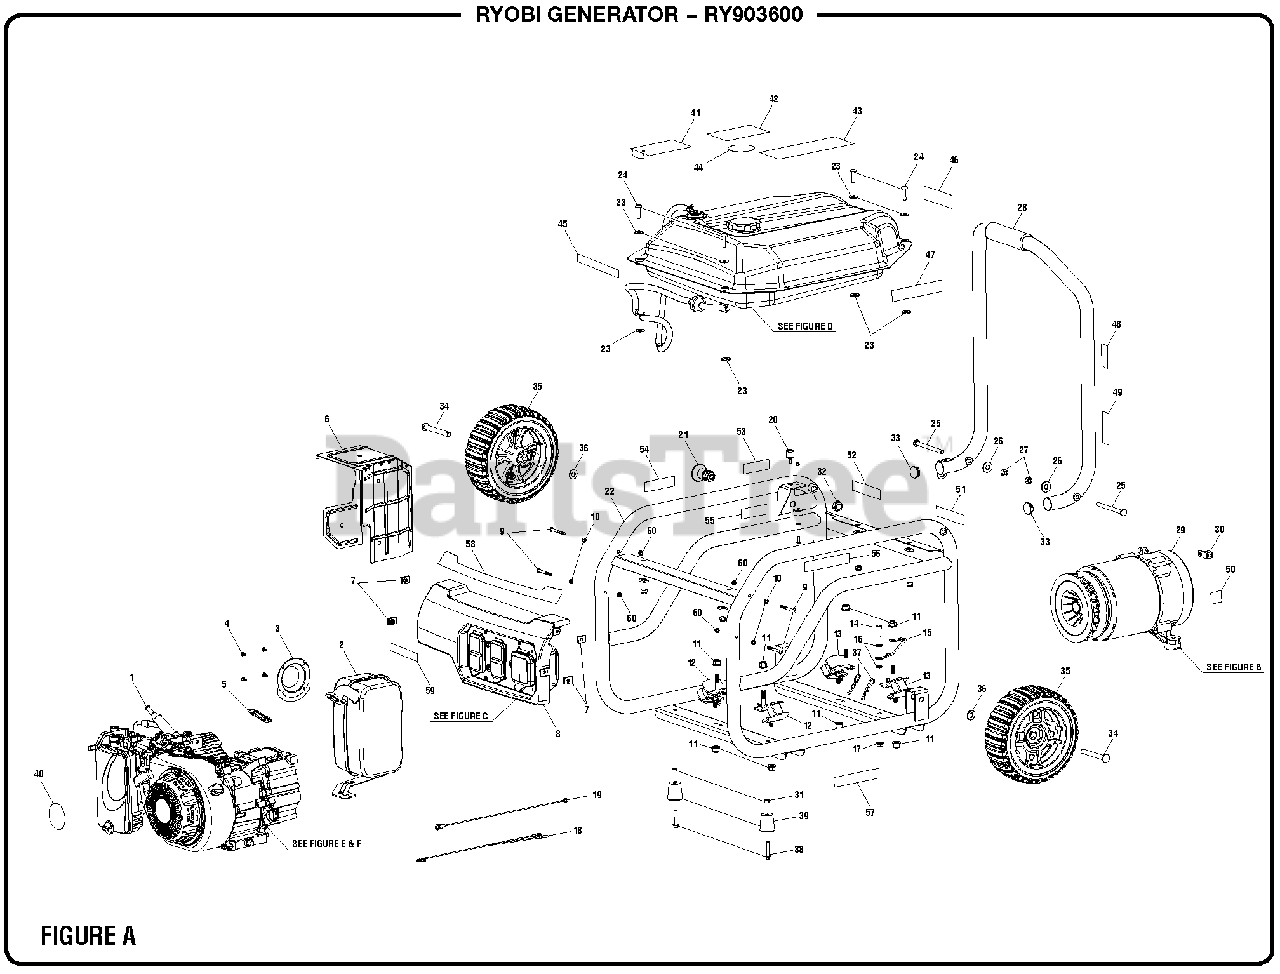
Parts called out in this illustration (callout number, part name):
3	Spark Arrester
4	Screw (8-32 x 3/8 in.)
5	Exhaust Gasket
6	Heat Shield
7	U-Clip (M6)
8	Control Panel Assembly
9	Screw (M5 x 35 mm)
10	Washer (ID5.3 x OD10 x 0.5t)
11	Lock Nut (M8)
12	Isolator (Right)
13	Isolator (Left)
14	Bolt (5/16-18 X 0.75 in.)
15	Ground Wire Assembly
16	Star Washer (5/16 in.)
17	Flange Nut (5/16-18)
18	Wire Assembly (Black)
19	Wire Assembly (Green)
20	Handle Bumper
21	Quick Release Pin
22	Carrier Assembly
23	Washer (1/4 in., Type A)
24	Screw (1/4-20 x 1 in., T30 Torx Hd.)
25	Handle Pivot Bolt
26	Washer (5/16 in.)
27	Lock Nut (5/16-18)
28	Handle Assembly
29	Generator Head Assembly
30	Ground Lug
31	Lock Nut (M8)
32	Lock Nut (1/2-20)
34	Axle Bolt
36	Washer (M10)
37	Hitch Pin
38	Bolt (M8 x 45 mm, Hex Flange Hd.)
40	Recoil Label
41	Notice Hangtag
42	Warning Label
43	CPSC Label
44	Fuel Stabilizer Label
45	Logo Label
46	Combustion Warning Label
47	Start Label
48	Fuel Stabilizer Label (SP/FR)
49	E85 Label
50	Ground Label
51	Ground Warning Label
52	Fire Danger Label
53	Pin Release Label
54	Inquiries Label
55	Hot Surface Label
56	Fire Distance Label
57	Lubricant Label
58	Performance Label
59	Choke Label
60	Lock Nut (1/4-20)
